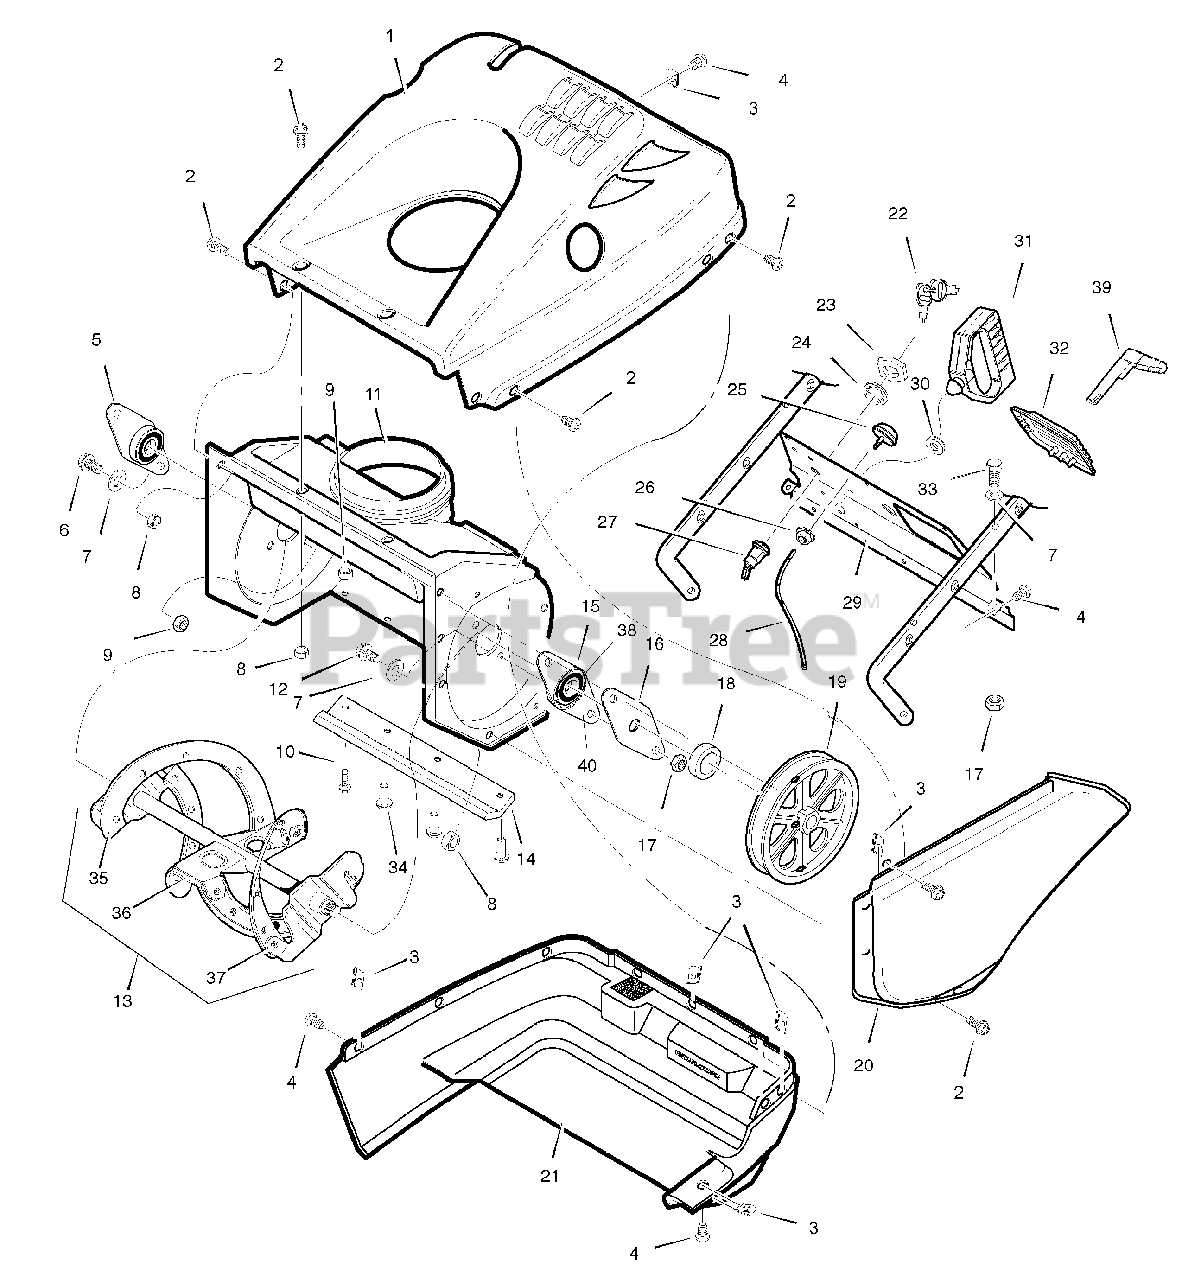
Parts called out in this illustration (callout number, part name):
1	COVER, Top, Red
2	SCREW, #10-24 x 1/2
3	NUT, Speed, 1/4-10
4	SCREW, 1/4-14 x 3/4
5	FLANGE BEARING
6	SCREW, 1/4-20 x 1
7	WASHER, FLAT
8	NUT, Hex, Control Lock, #10-24
9	NUT, Hex, Control Lock, 1/4-20
10	SCREW, 1/4-20 x 3/4
11	AUGER HOUSING ASSEMBLY
12	SCREW, 1/4-20 x 5/8
13	AUGER ASSEMBLY, Complete
14	BLADE, Scraper
15	ASSEMBLY, Bearing & Plate
16	PLATE & RETAINER BEARING ASSEMBLY
17	NUT, Hex, 1/4-20
18	SPACER, Sleeve
19	PULLEY, 6" OD
20	COVER, Belt
21	COVER, Bottom
22	SET, Key
23	NUT, 5/8-32
24	WASHER
25	PRIMER, Carburetor
26	NUT, Hex, 1/-20
27	SWITCH, Ignition
28	HOSE, Primer 9.5"
29	CONTROL PANEL
30	GROMMET & WASHER, Rope
31	GRIP, Starter Rope
32	PANEL, Spark Plug Access
33	SCREW, 1/4-20 x 1-1/4
34	RIVET, Offset
35	BLADE, Auger
36	BLADE, Center
37	RIVET, Offset
38	BEARING, Ball
39	KNOB, Choke Shaft
40	RETAINER, Bearing
